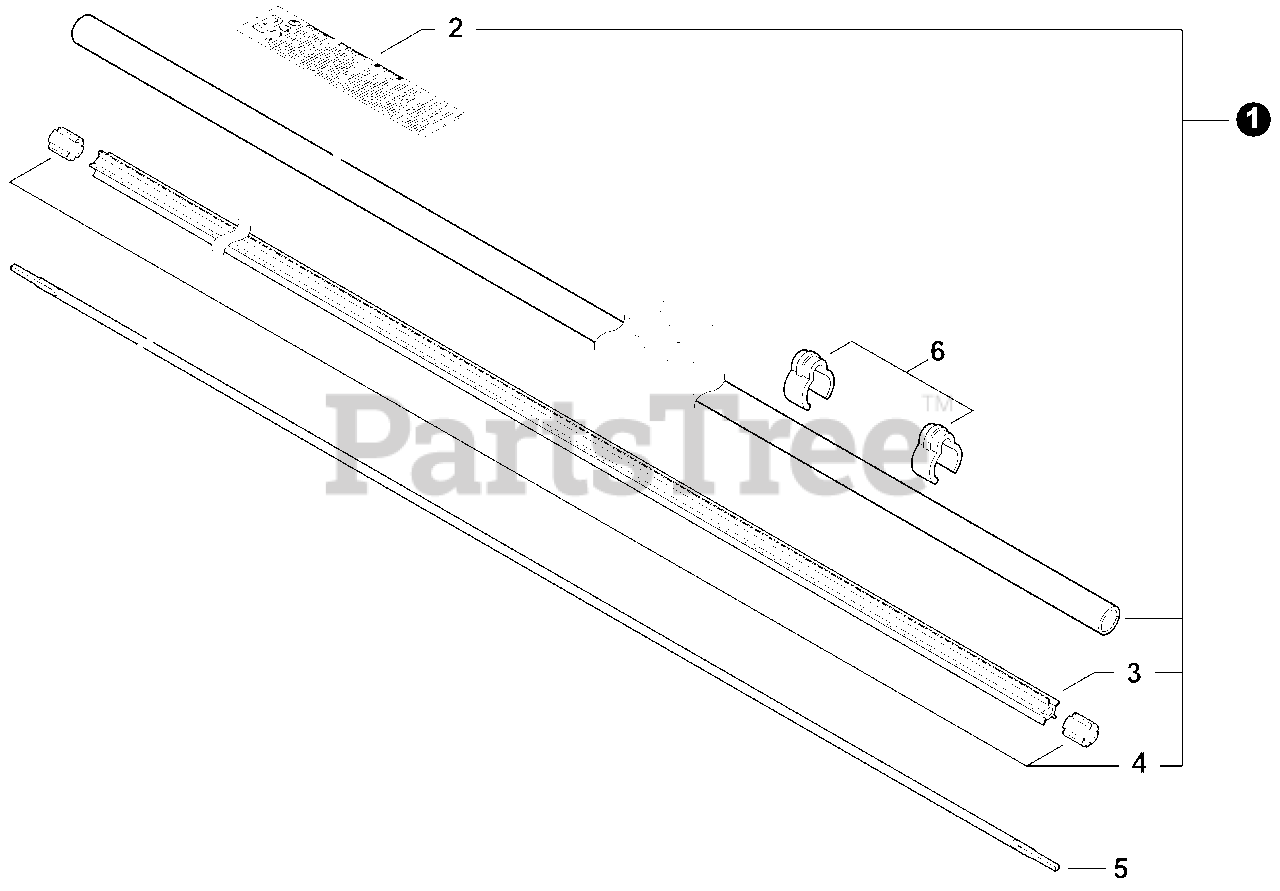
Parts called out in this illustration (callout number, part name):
1	MAIN PIPE ASSY
2	LABEL, CAUTION
3	LINER, FLEXIBLE 21.6×1420
5	DRIVESHAFT - FLEXIBLE
6	CLIP, CABLE 25 MM
